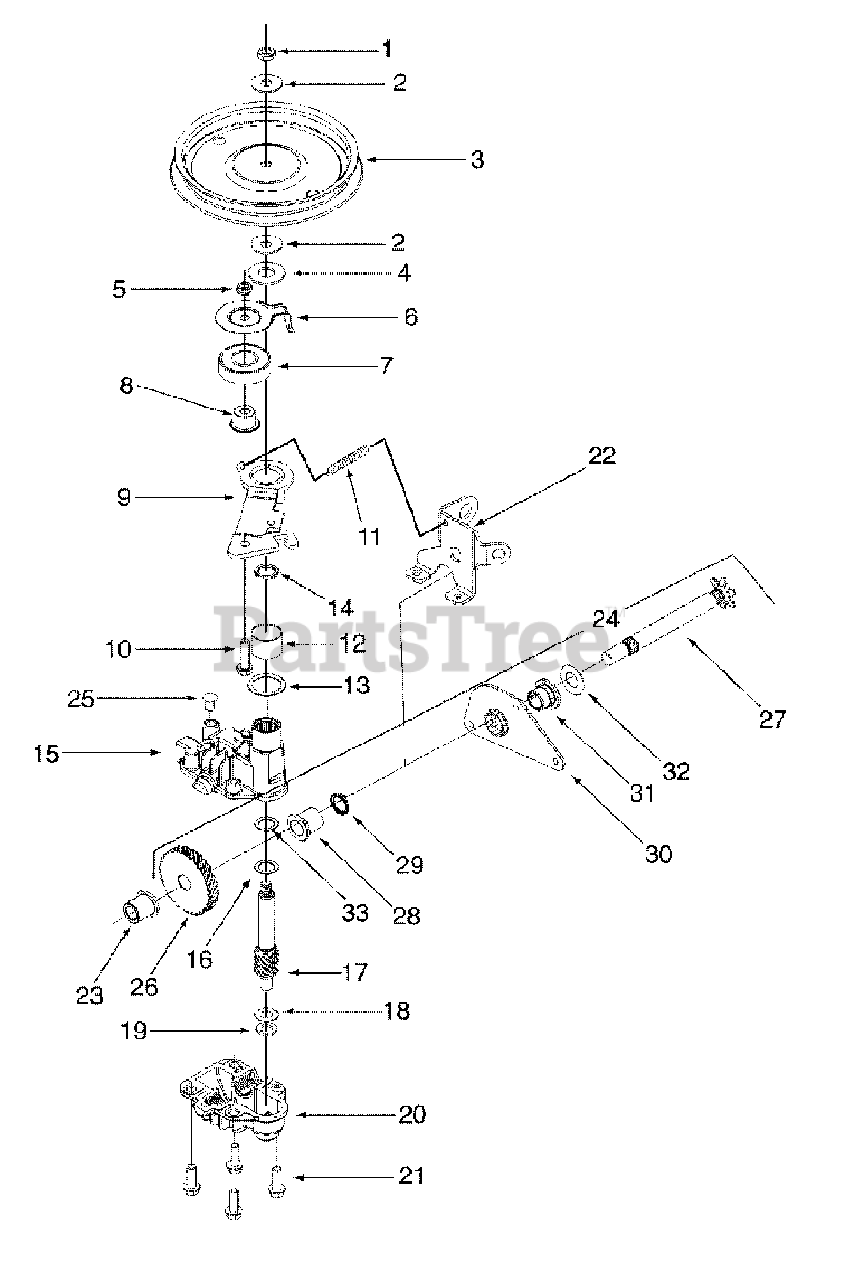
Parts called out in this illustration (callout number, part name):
1	Hx . Jam Nut 5/16-24
2	Bell Wash. .325 x .930 x .045
4	Fl. Wash. .510 x 1.120 x .060
5	Hx . Jam Nut 1/4-28
7	Bearing
8	Flange Spacer
9	Idler Bracket Assembly
10	Hx . Cap Scr. 1/4-28 x 1.00 Gr. 5
11	Extension Spring
12	Bearing Sleeve
13	Fl. Wash. .885 x 1.145 x .030
14	Oil Seal
15	Upper Housing Assembly
16	Thrust Wash. .504 x .700 x .030
17	Pinion Shaft 10T.
18	Thr. Wash. 3/8 x .70 x .030
19	Thr. Wash. .388 x .625 x .062
20	Lower Housing Assembly
21	Hx . Scr. 1/2-20 x .75
24	Shaft Assembly
27	Output Shaft 6T.
28	Flange Bearing
29	Oil Seal
30	Pivot Bracket
31	Flange Bearing
32	Wash. Fl. .508 I.D. x 1.00 O.D. x .020
33	Bearing
